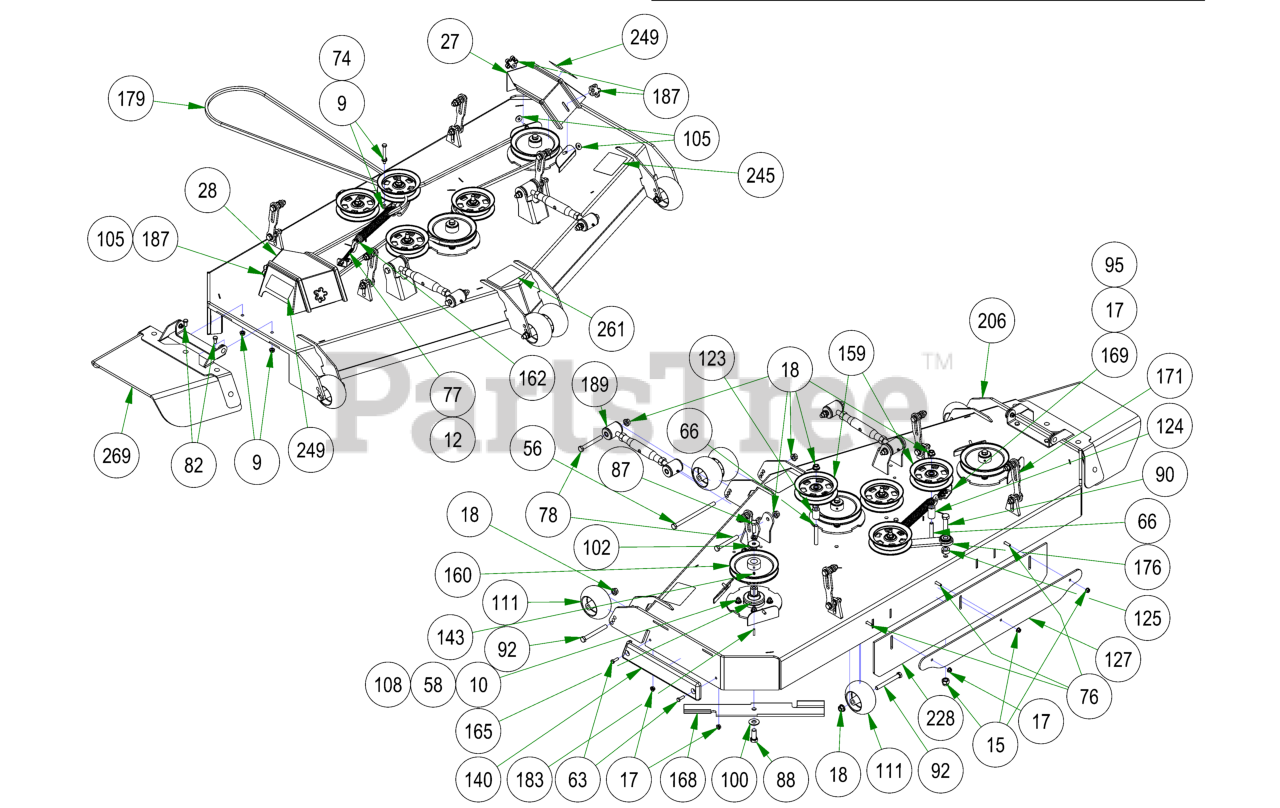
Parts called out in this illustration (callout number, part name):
9	3/8-16 HEX SERRATED FLANGE NUT HARD/ZINC
10	3/8-16 NYLON INSERT FLANGE LOCKNUT (GR.F) ZINC
12	3/8-16 HEX NUT ZINC
15	5/8-11 NYLON INSERT LOCKNUT ZINC
17	5/16-18 NYLON INSERT FLANGE LOCKNUT ZINC
18	1/2-13 NYLON INSERT FLANGE LOCKNUT ZINC
27	2019 72" Left Outlaw Gen2 Pulley Cover
28	2019 72" Right Outlaw Gen2 Pulley Cover
56	1/2-13 X 8 HEX CAP SCREW GR 5 ZINC
58	3/8-16 X 1-3/4 HEX C/S (GR.5) ZC
63	5/16-18 X 1 HEX CAP SCREW (GR.5) ZINC
66	1/2-13 X 3-1/2 HEX FLANGE BOLT (GR.8) ZINC
74	3/8-16 X 3 HEX CAP SCREW (GR.5) ZINC
76	5/16-18 X 1-1/4 CARRIAGE BOLT ZINC
77	4" 3/8-16 Eye Bolt
78	1/2-13 X 4 HEX CAP SCREW (GR.8) ZINC YELLOW
82	3/8-16 X 3/4 HEX CAP SCREW (GR.5) ZINC
87	1/2-20 X 1-1/2 HEX CAP SCREW (GR.5) ZINC
88	5/8-18 X 1-1/2 HEX CAP SCREW (GR.8) ZINC YELLOW
90	5/8-11 X 2-1/2 HEX CAP SCREW (GR.5) ZINC
92	1/2-13 X 4-1/2 HEX CAP SCREW (GR.5) ZINC
95	5/16-18 X 7/8 CARRIAGE BOLT ZINC
97	1/2 SPLIT LOCKWASHER (GR.8) ZINC/YELLOW
100	5/8 USS FLAT WASHER (1-3/4" OD) GR.8 ZINC YELLOW
102	1/2 BELLEVILLE WASHER (1-5/8 OD X .140 THK) ZINC
105	.360 ID X .983 OD X .120 THICK FLAT WASHER NYLON BLACK
108	5/16 USS FLAT WASHER (7/8 OD) ZINC
111	2019 Deck Wheel
123	.502 ID X .750 OD X 1.500 Long Spacer
124	1 3/4" Pulley Spacer
125	5/8 SOLID SHAFT COLLAR (W/1 SET SCREW) ZINC
127	61 Bolt in Baffle Deck v2 Stripping Plate
140	REVISED TRIM BUMPER_20180226
143	5/16-24 X 1/4 SOCKET SET SCREW (CUP PT) PLAIN
159	5-3/4 Idler Pulley
160	7" Deck Pulley
162	2019 Outlaw Gen2 Deck Spring
165	OUTLAW SPINDLE ASSEMBLY
168	72" High Lift Fusion Blade
169	2019 Deck Eye Bolt Tab
171	Deck Hangar Assembly
176	2019 Rebel Rogue Deck Idler
179	B202 Belt for 72" Outlaw
183	1/4 X 1 SQ MACHINERY KEY 1018 STL PLN
187	5/16" Knob
189	Turnbuckle
206	2019 Sloped 72" Deck
228	R Series Rubber For Deck
245	2018 72" Deck Decal
249	Danger Decal-Spindle/Discharge
261	2019 Rebel & Rogue Deck Belt Route Decal
269	2019 Outlaw Gen2 Chute Assembly
